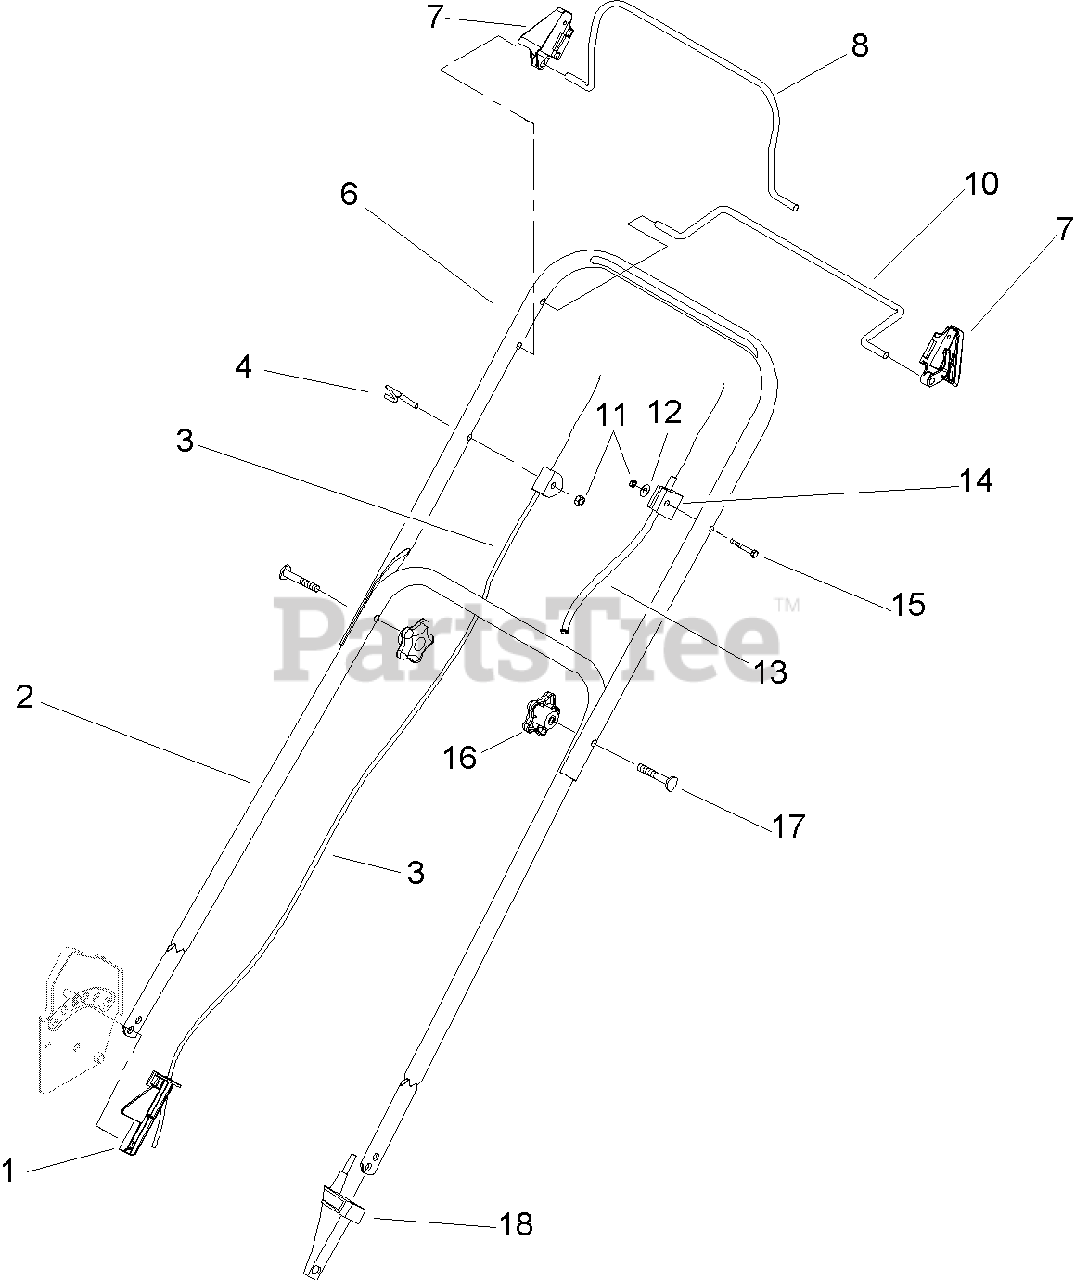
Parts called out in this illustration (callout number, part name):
1	GUARD-CABLE
2	HANDLE-LOWER
3	BRAKE CABLE ASM
4	GUIDE-ROPE
6	HANDLE-UPPER
7	STOP-PIVOT
8	BAIL-BRAKE
10	BAIL-CONTROL
11	NUT-LOCK, NI
12	WASHER-FLAT
13	CABLE-GROUND SPEED
14	ANCHOR-CABLE, UPPER
15	SCREW-HH
16	KNOB-HANDLE
18	ANCHOR-CABLE
